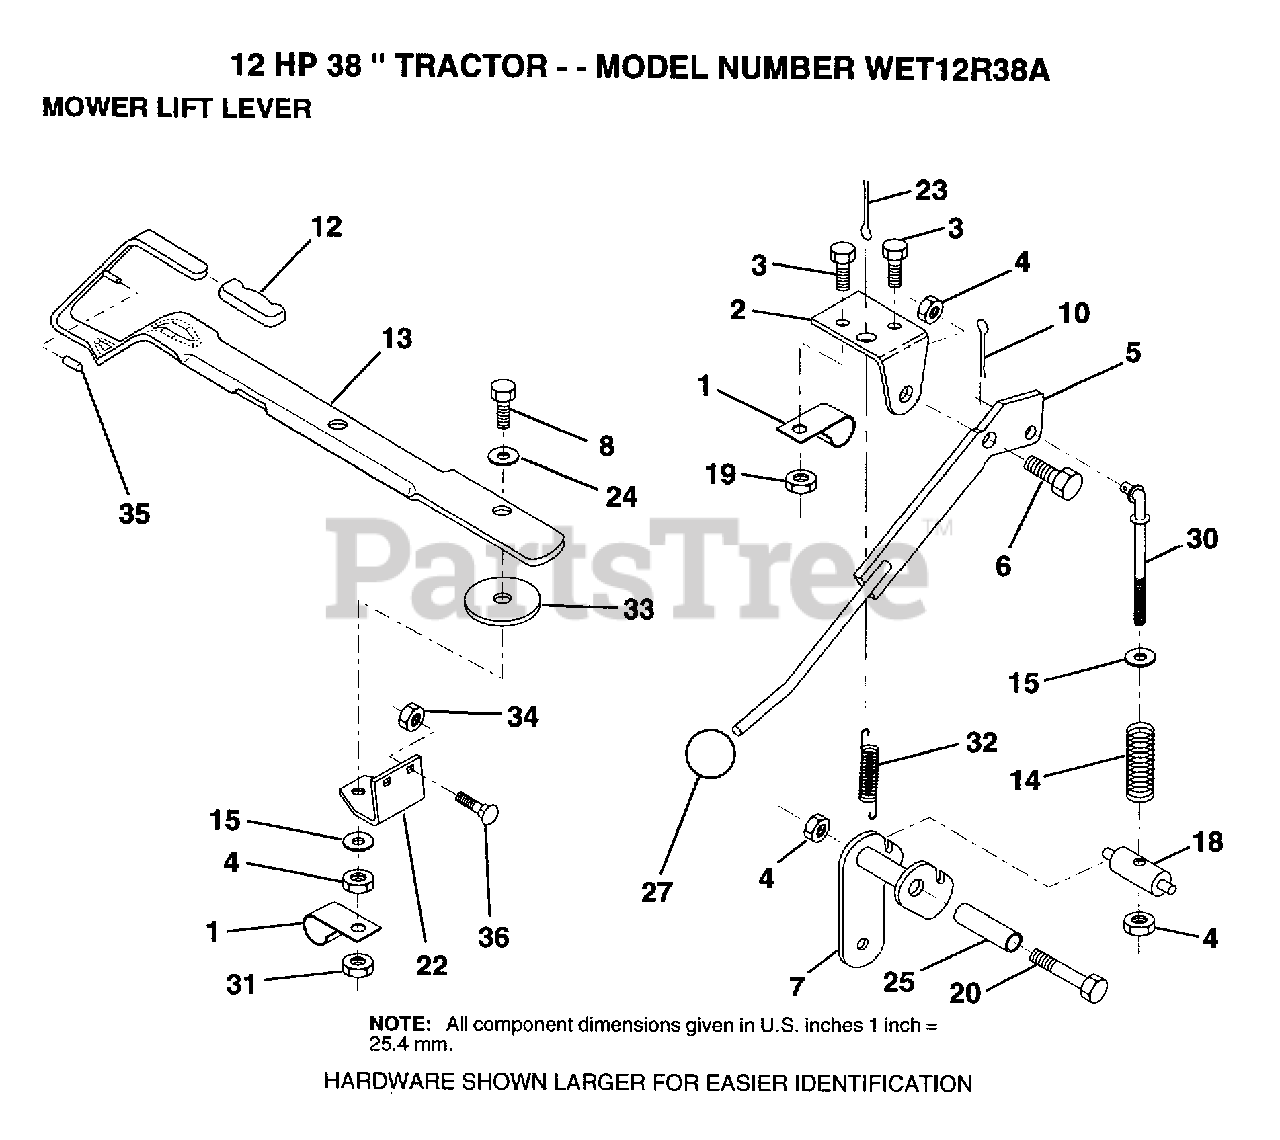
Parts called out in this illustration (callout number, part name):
1	"CLIP,INSULATOR"
2	BRKT CLUTCH
3	BOLT
5	CLUTCH LEVER AS
6	"BOLT, SHOULDER LT"
7	MWR CLUT ARM ASM
8	BOLT
10	COTTER PIN
12	GRIP HANDLE
13	LEVER LIFT LR
14	COMP CLUTCH SPRNG
15	WASHER HYT
18	TRUNNION
20	BOLT
22	LIFT LEVER BRKT
24	WASHER
25	TUBE SPACER
27	KNOB T(3/8 HOLE)
30	ROD TENSION CLUTC
31	LOCKNUT
32	SPRING EXT
33	WASHER
35	VINYL CAP RED
36	BOLT
